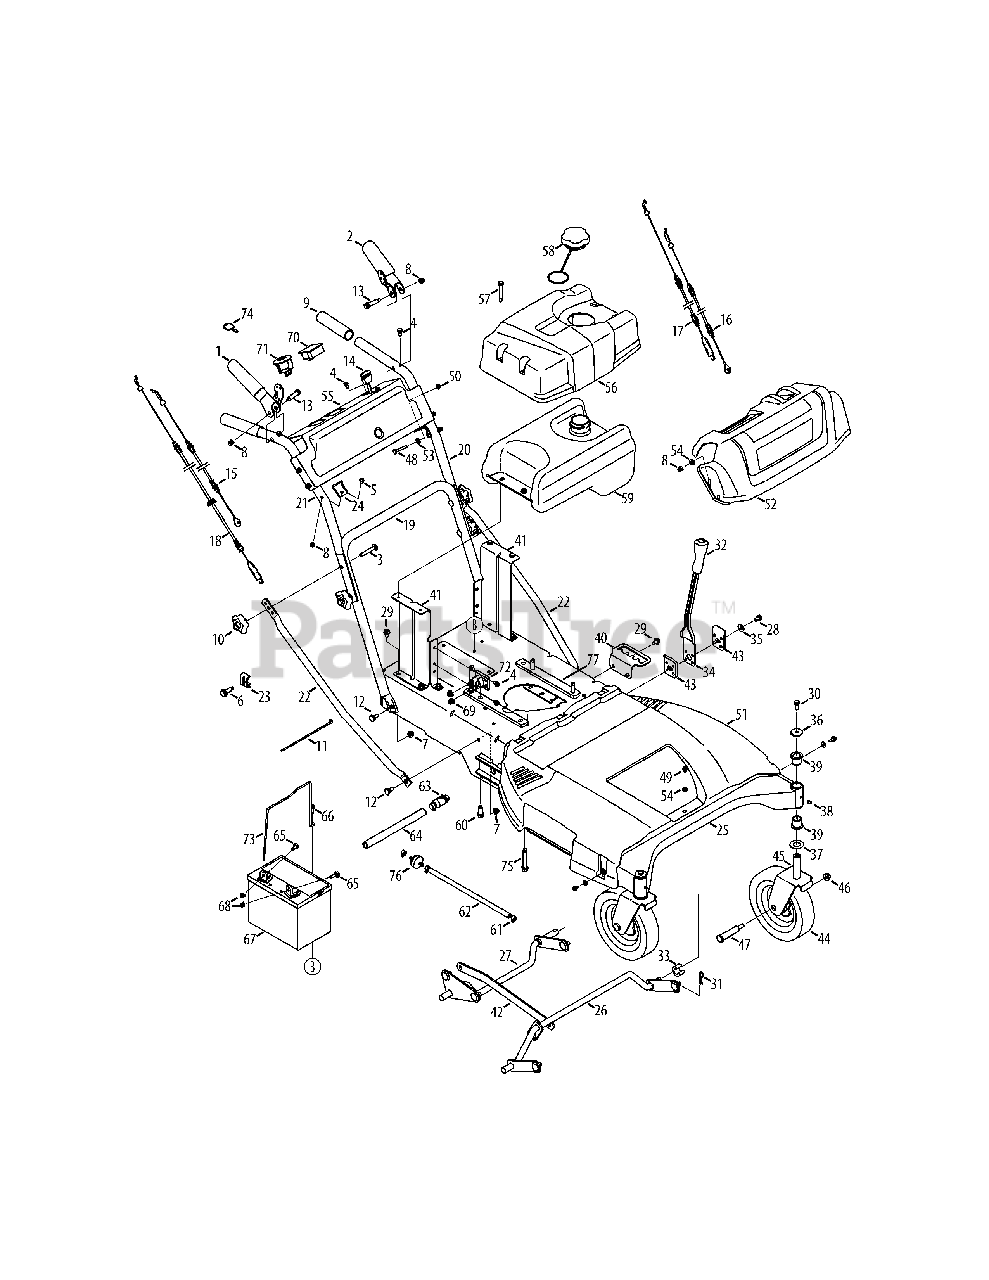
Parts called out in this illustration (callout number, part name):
1	RH Lever Assembly Bracket
2	LH Lever Assembly Bracket
3	Screw, Carriage, 5/16-18 x 2.25
4	Screw, 1/4-20 x 0.500
5	Hex Screw, 1/4-20 x 1.50
6	Screw, #10-32 x 0.625
7	Nut, Flangelock, 5/16-18
8	Lock Nut Cap, 1/4-20
9	Grip, 1.0 ID x 5.0 LG
10	Star Knob, 5/16-18
11	Cable Tie, 3/16 x .05 x 7.4
12	Screw, Shoulder, .435 x .178-5/16 x .56
13	Screw, Shoulder, .375 x 1.355 x 1/4-20
14	Throttle/Choke Cable, 38.0 x 1.1 EXT
15	RH Brake Cable, Tecumseh Trans.
16	LH Brake Cable, Tecumseh Trans.
17	Wheel Clutch Cable
18	Deck Clutch Cable
20	Upper LH Handle
21	Upper RH Handle
22	Adjustable Handle Brace
23	Casing Clamp
24	RH Cable Mount Bracket
24	LH Cable Mount Bracket
25	Frame Assembly, Tecumseh
26	Front Deck Lift Assembly
27	Rear Deck Lift Assembly
28	Hex Screw, 5/16-18 x .50
29	Screw, 5/16-18 x 0.625
30	Hex Screw, 5/16-24 x .750
31	Click Pin, .092 x 1.64 LG
32	Grip Handle, 1/2
33	Plastic Spacer, .63 ID x .75 LG
34	Deck Height Lever
35	Washer, Bell, .340 x .872 x .060
36	Washer, Flat, .330 x 1.25 x .120
37	Washer, Flat, .760 ID x 1.50 OD
38	Drive Lube Fitting, 3/16
39	Flange Bearing, .760 x .941 x 1.0
40	Height Adjustment Bracket
41	Fuel Tank Mount Bracket
42	Link Pivot Bracket
43	Lever Pivot Bracket
44	Caster, Wheel, 8 x 1.75
44	Bearing, Flange w/ftg
45	Wheel Caster Bracket
46	Nut, Flangelock, 3/8-16
47	Bolt, Shoulder, .625 x 2.515 x 3/8-16
48	Hex Screw, 1/4-20 x 1.75
49	Screw, 1/4-14 x 0.625
50	Nut, Hex, 1/4-20
51	Belt Cover
52	Handle Panel, Black
53	Washer, Bell, .265 x .75 x .062
54	Washer, Flat, .25 x .630 x .0515
55	Hour Meter and Key Handle Panel
56	Fuel Tank Cover
57	Screw, Shoulder, 1/4-20 x .32 x 1.8
59	Fuel Tank
60	Screw, 3/8-16 x 1.250
61	Hose Clamp, .490 DIA.
62	Fuel Hose, Low Permeation, 1/4
64	Extension Hose
65	Hex Head Flange, 1/4-20 x .75
66	Screw, 1/4-20 x 0.750
67	Battery, 155 CCA WET
68	Sems Nut, 1/4-20
69	Nut, Flangelock, 1/4-20
71	Key Switch
72	Solenoid, 12V, 100 AMP
73	Battery Hold Down Strap
75	Screw, 3/8-16 x 2.25
76	Fuel Filter
